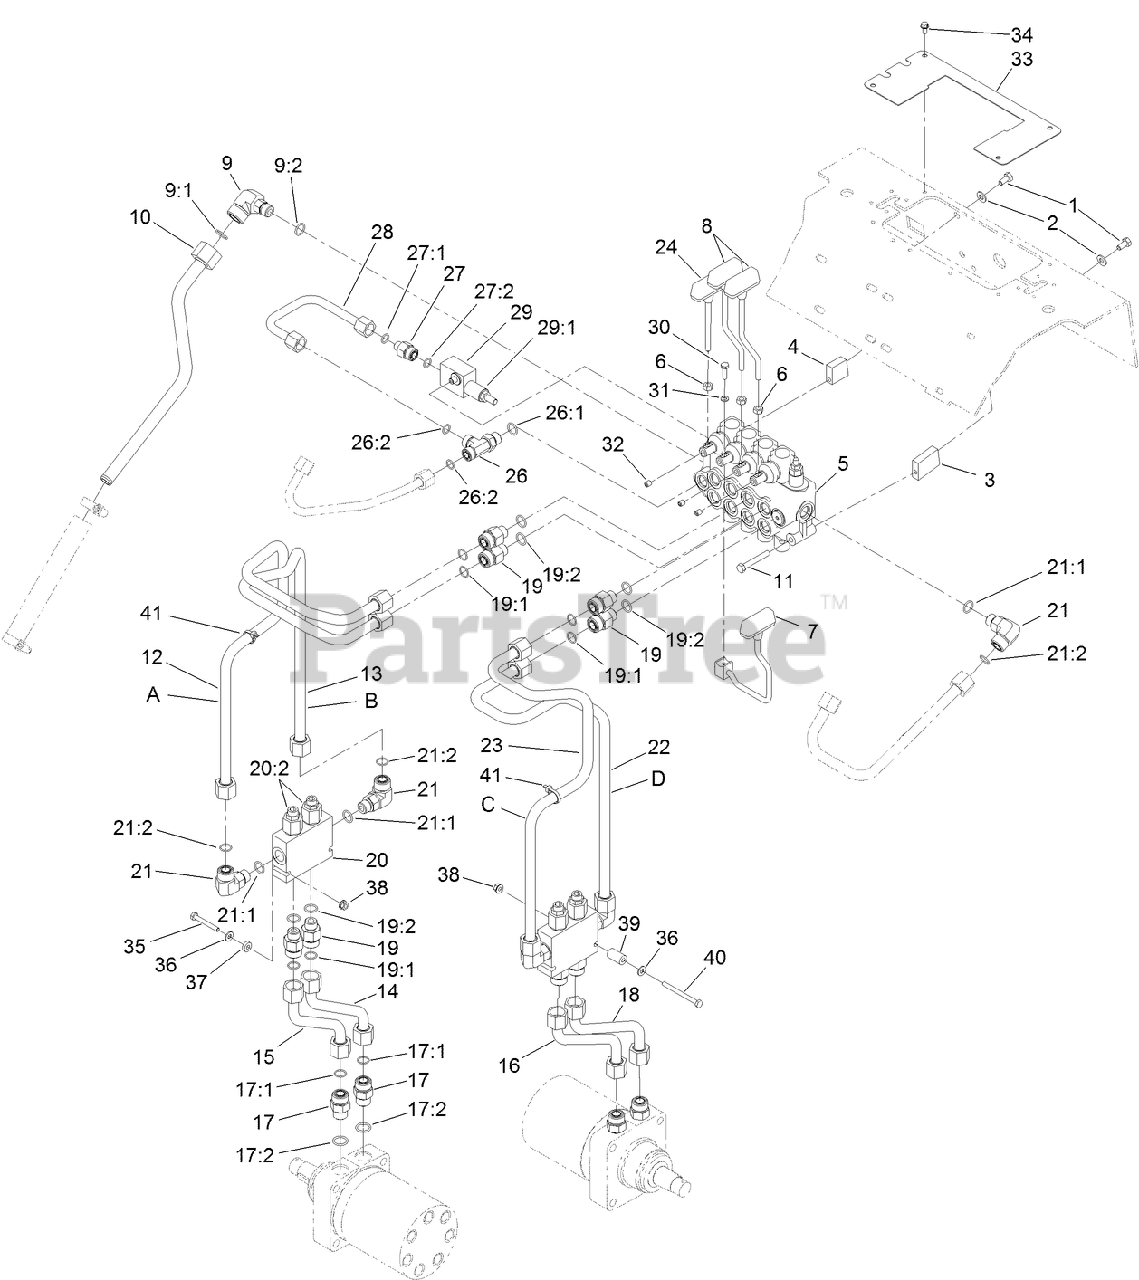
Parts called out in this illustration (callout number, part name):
1	SCREW-HH
2	WASHER-PLAIN
3	SPACER
4	SPACER-UPPER
5	VALVE-FOUR SPOOL (W/ RELIEF PORT)
6	NUT-HEX
7	LEVER-CONTROL
8	LEVER-DRIVE
9	FITTING-HYD, 90 DEG
9:1	O-RING
9:2	O-RING
10	TUBE-TANK, HYD
11	SCREW-HH
12	TUBE-HYD (RIGHT B)
13	TUBE-HYD (RIGHT A)
14	TUBE-HYD
15	TUBE-HYD
16	TUBE-HYD
17	FITTING-STRAIGHT
17:1	O-RING
17:2	O-RING
18	TUBE-HYD
19	FITTING-STR
19:1	O-RING
19:2	O-RING
20	VALVE-COUNTERBALANCE
20:2	VALVE-CARTRIDGE
21	Fitting-Elbow, 90 DEG
21:1	O-RING
21:2	O-RING
22	TUBE-HYD (LEFT A)
23	TUBE-HYD (LEFT B)
24	LEVER-CYLINDER
26	FITTING-TEE
26:1	O-RING
26:2	O-RING
27	FITTING-STR
27:1	O-RING
27:2	O-RING
28	TUBE-HYD
29	RELIEF VALVE ASM
29:1	CARTRIDGE-VALVE, RELIEF
30	SCREW-HH
31	WASHER-LOCK
32	SCREW-SET, HSH
33	PLATE-COVER
34	SCREW-HWH
35	SCREW-HH
36	WASHER-FLAT
37	SPACER
38	NUT-HHF
39	SPACER
40	SCREW-HH
41	TIE-CABLE
